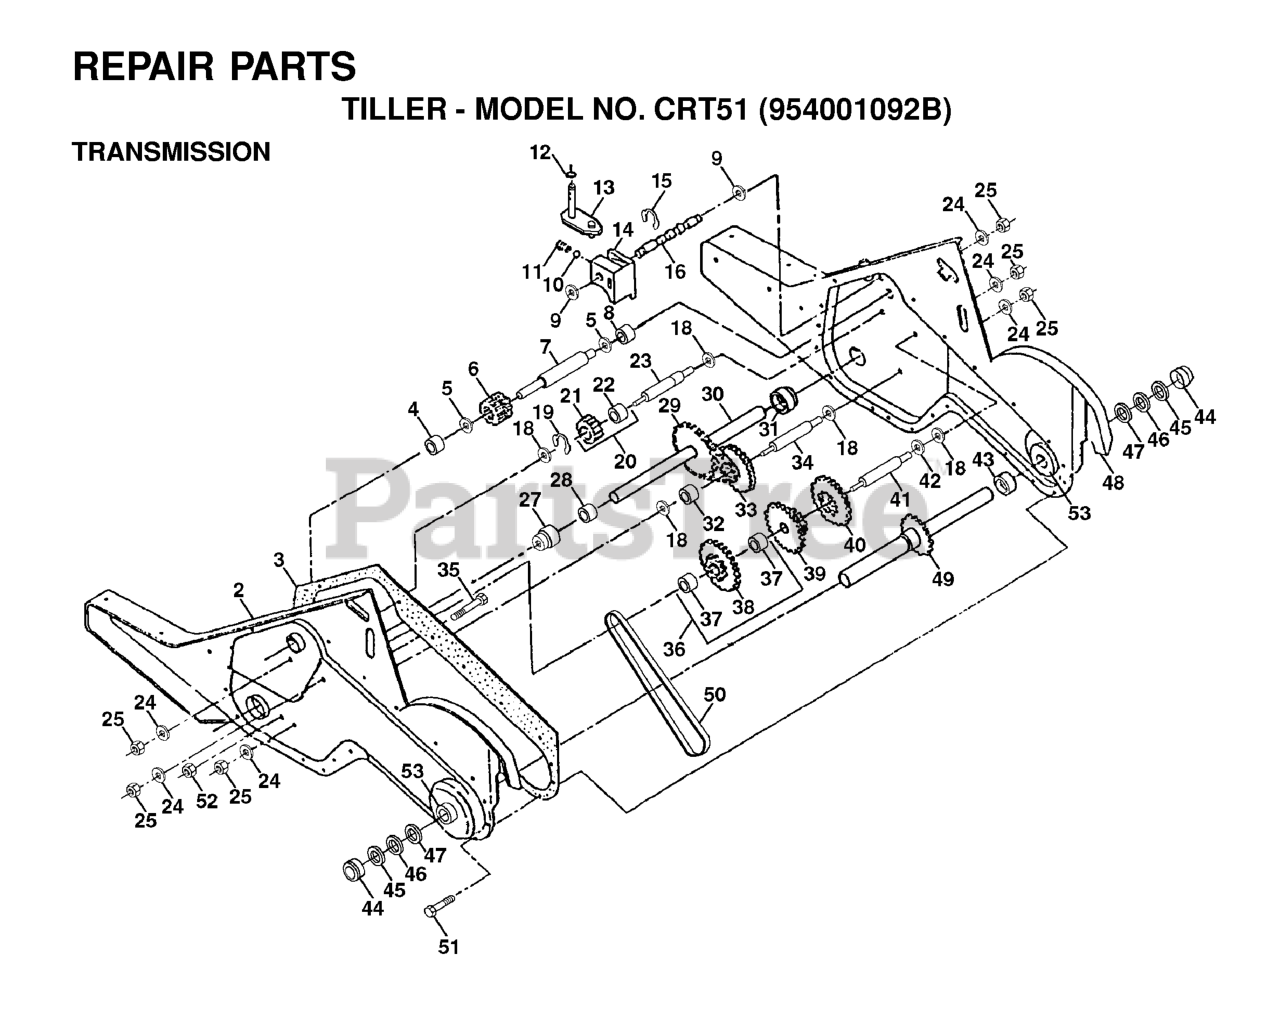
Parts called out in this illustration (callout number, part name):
1	SPRING.INTERLOCK
2	CAM.INTERLOCK.RELEASE
3	SPRING.TORSION.LEVER
4	SPRING RETAINER
5	SCREW 14-20 X 5/8
6	STOP.INTERTLOCK
